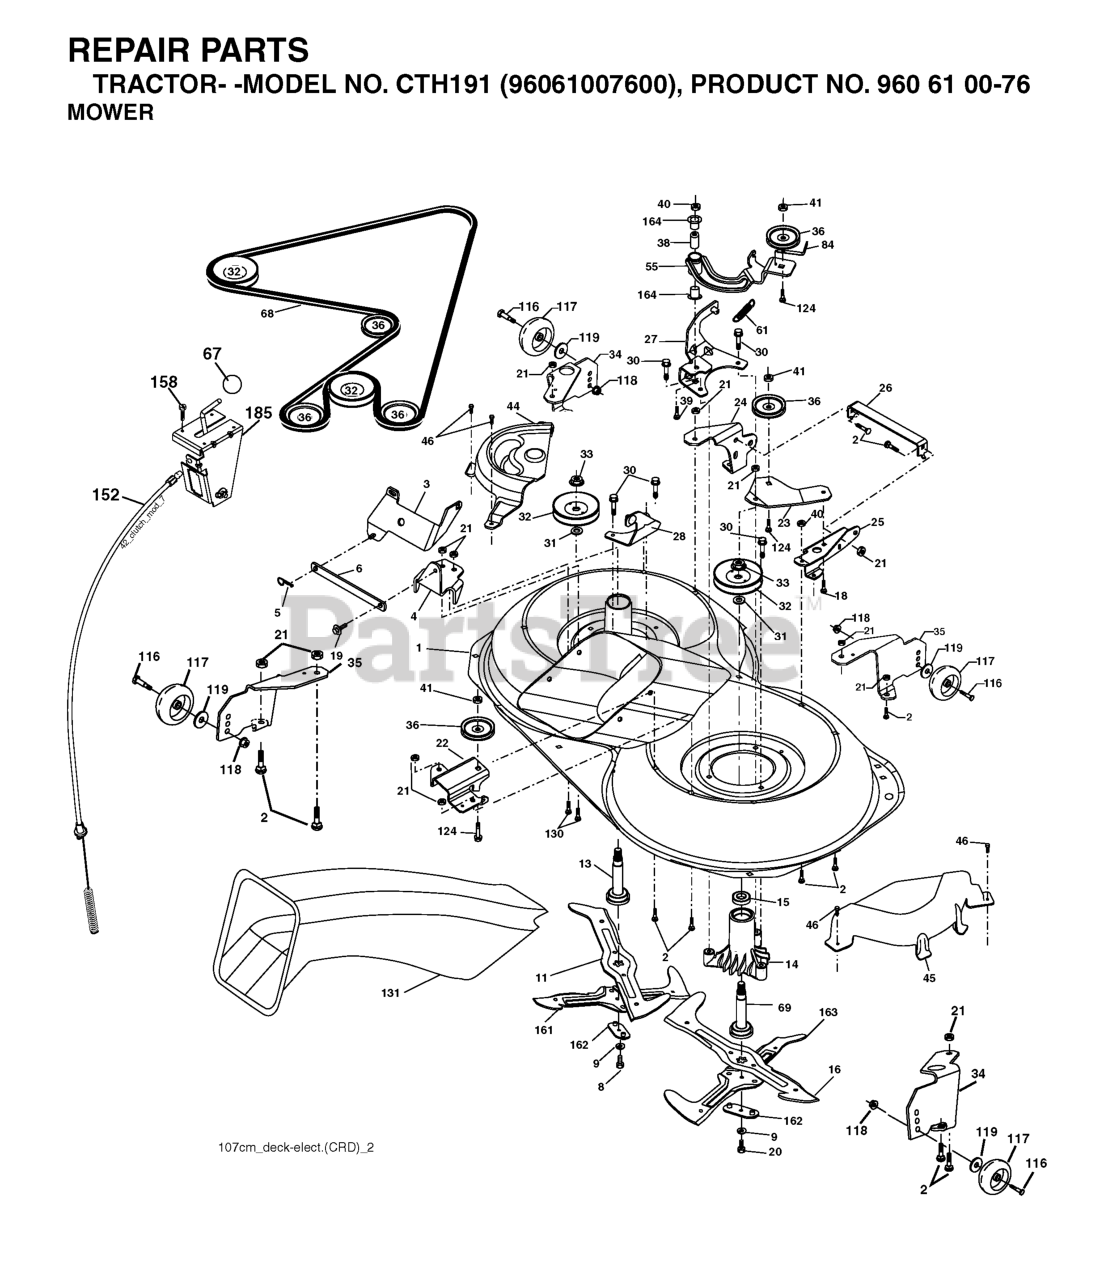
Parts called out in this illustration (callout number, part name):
1	Housing Asm. Mower 107 CRD
2	RP BOLT 5/16-18 X3/4 ZN/YEL GR
5	RETAINER-SPRNG RB
6	BAR.SWAY.92.CRD
8	BOLT.3/8-24X1.25 GR8
9	LOCKWASHER
11	BLADE.3N1.LH.CRD
13	SHAFT ASM VENT
14	HOUSING.MANDREL.VENTED (MACHD)
16	BLADE.3N1.RH.CRD
19	BOLT SHD 5/16-18
20	BOLT.3/8-24X1.25GR8. LHTHRD
21	LOCKNUT
22	BRACKET.IDLER.RR.107.CRD
25	BRACKET RF
26	SUPPORT
28	BRACKET
30	SCREW, WASHER HEAD
31	WASHER.SPACER.MANDREL
32	PULLEY.MANDREL.4.80 PD.2006
33	NUT.FLANGE.LOCK.TOP
34	BRACKET
35	BRACKET
36	PULLEY.IDLER.4.25
41	NUT LOCK FLG 3/8-16 UNC
45	COVER.MANDREL.RH.CRD
46	SCREW.1/4-20X5/8
55	ARM.IDLER.107.CRD
61	SPRING
67	KNOB T (3/8 HOLE)
68	HEX-BELT 107 MOWER
69	SHAFT.ASM.W/LWR.BRG.RH.THREAD
84	KEEPER, BELT IDLER
116	SHOULDER BOLT
117	RP WHEEL. GUAGE RALLY
118	LOCKNUT
119	WASHER.5/16.FLAT.STE.STD.
124	BOLT.3/8-16X1.50
130	BOLT.CARR.SQNK.5/16-18UNC.X3/4
131	CHUTE BAGGER
158	SCREW
163	BLADE.CROSS.RH.CRD.107
164	BRNG T
185	HEAD ASM. CABLE CLUTCH
